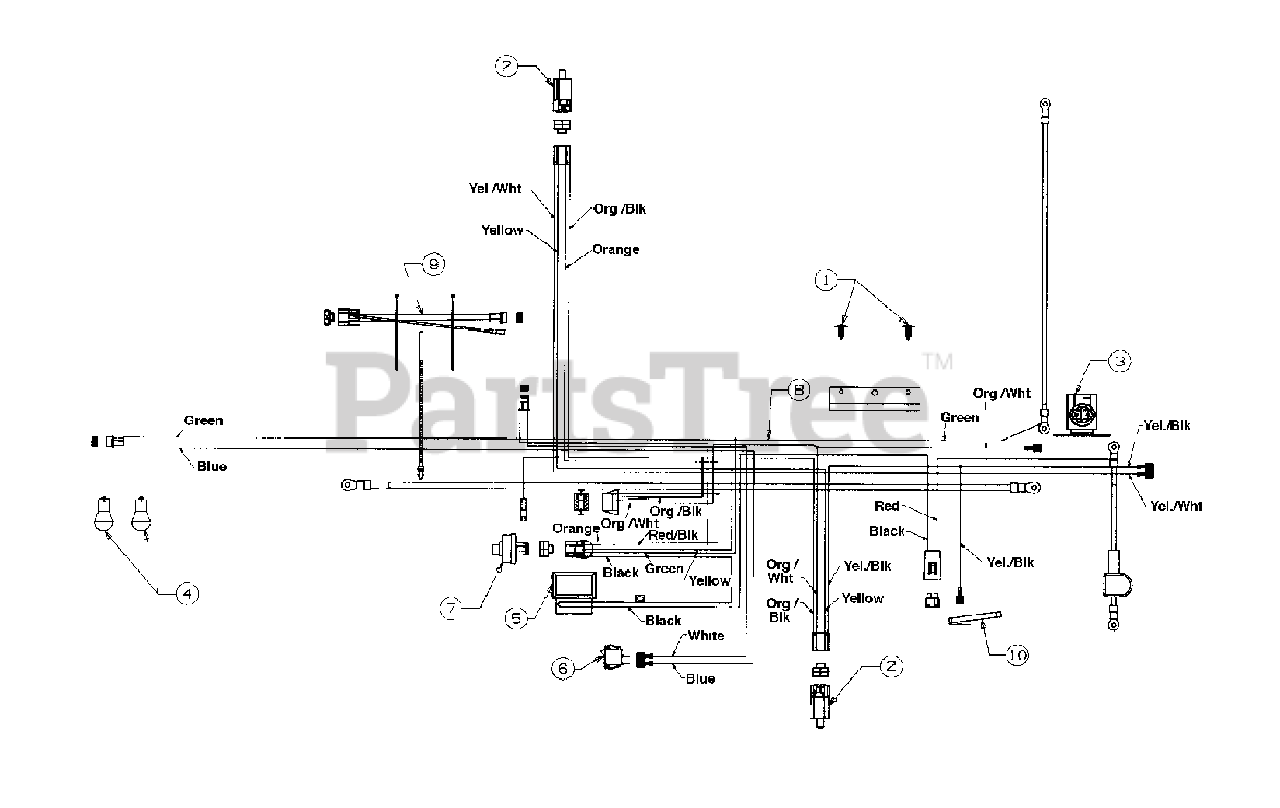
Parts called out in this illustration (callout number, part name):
1	Ratchet
2	Safety Switch
3	Solenoid
4	Bulb (Headlight)
5	Ammeter
6	Light Switch
7	Ignition Switch
8	Wire Harness
9	Wire Harness Adapter
10	Wire Harness
